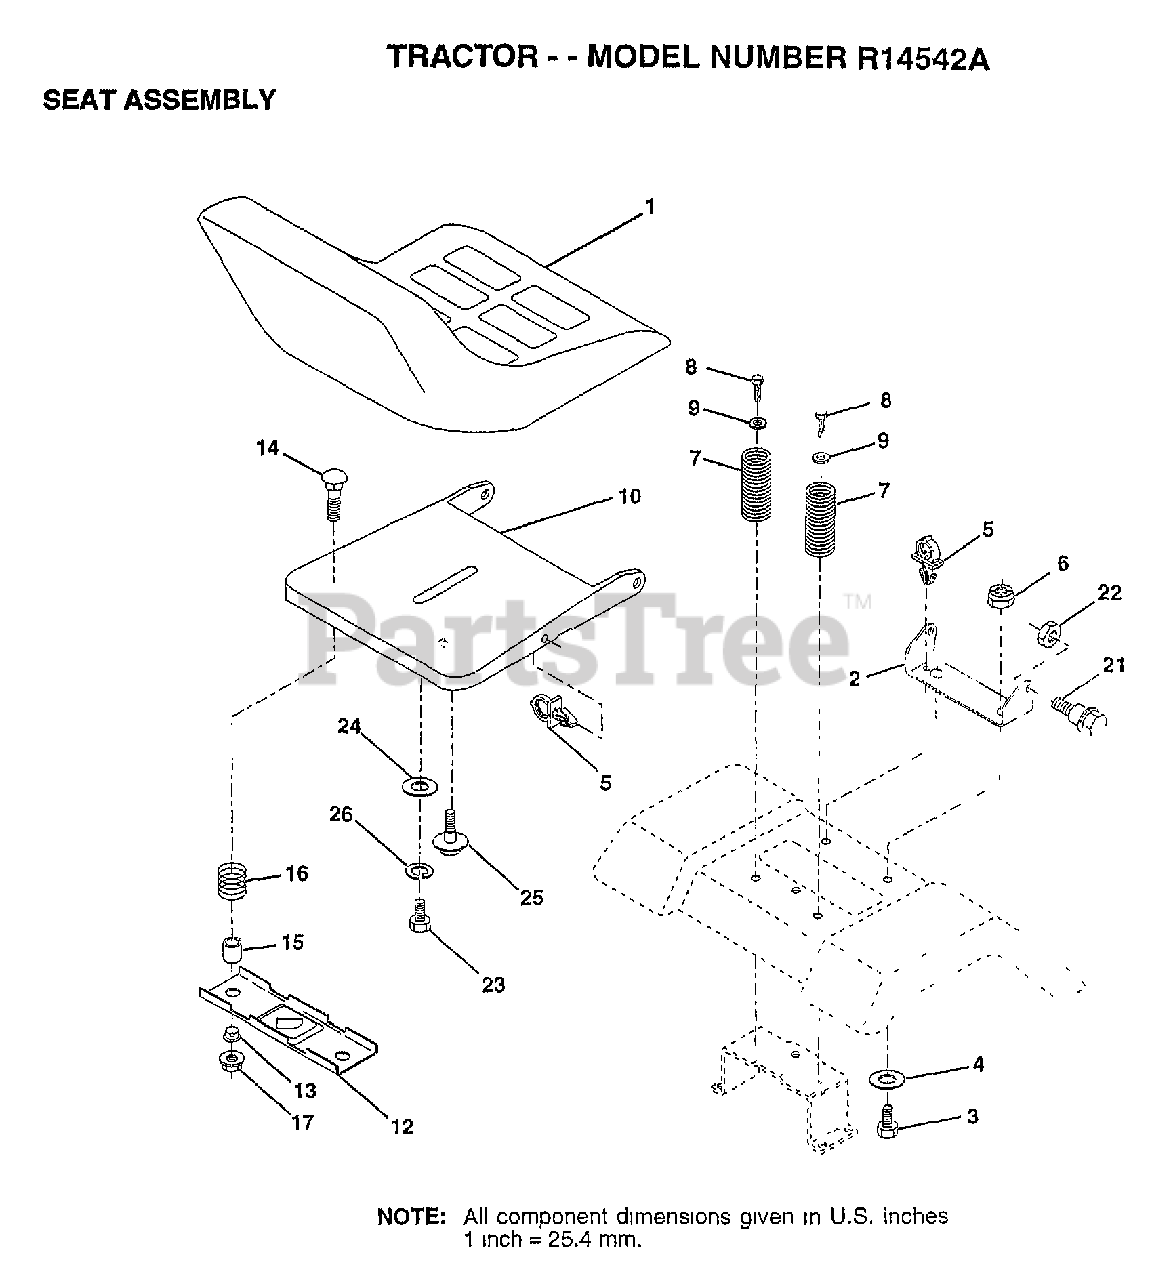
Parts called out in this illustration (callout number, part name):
2	BRACKET PVT SEAT
3	BOLT
4	WASHER PM
5	CLIP.PUSH-IN.HING
6	NUT
7	SPRING COMPRESSIO
8	SCREW GTV
9	WASHER
10	PAN-SEAT
12	BRKT SWITCH
13	BUSHING
15	SPLIT SPACER
16	SPRING
21	"BOLT,SHOULDER"
22	NUT
23	BOLT
24	WASHER
25	"BOLT,SHOULDER"
26	LOCKWASHER
